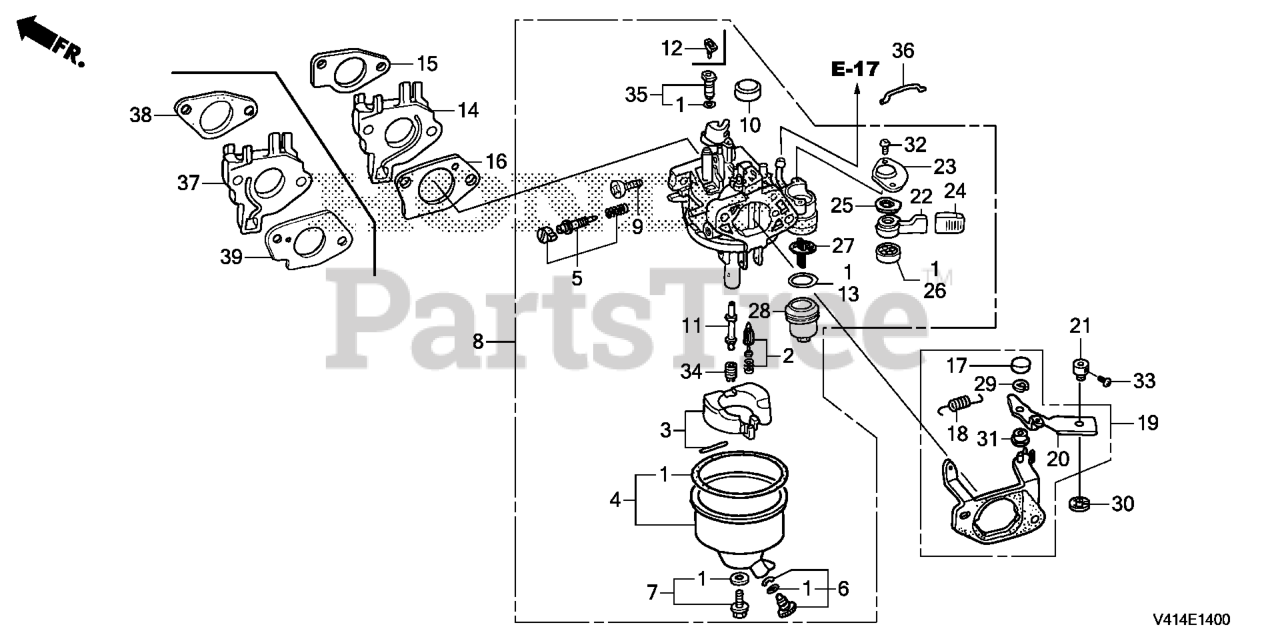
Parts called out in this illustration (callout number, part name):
1	GASKET SET (CARBURETOR NO.)
2	VALVE SET, FLOAT
3	FLOAT SET (CARBURETOR NO.)
4	CHAMBER SET, FLOAT
6	SCREW SET, DRAIN (CARBURETOR NO.)
7	SCREW SET (CARBURETOR NO.)
8	CARBURETOR ASSY. (BE75V A)
9	SCREW, THROTTLE STOP
10	CAP, CHOKE LEVER DUST
11	NOZZLE, MAIN
12	COLLAR, SET
13	GASKET, FUEL STRAINER CUP
17	CAP, CHOKE LEVER
18	SPRING, THROTTLE RETURN
19	STAY ASSY., CHOKE CONTROL (REMOTE)
20	LEVER, CHOKE
21	HOLDER, WIRE
22	LEVER, VALVE
23	PLATE, LEVER SETTING (CARBURETOR NO.)
24	CAP, LEVER
25	SPRING, PETCOCK LEVER (CARBURETOR NO.)
26	GASKET, VALVE
27	FILTER, CUP (CARBURETOR NO.)
28	CUP, FUEL STRAINER
29	E-RING (4MM)
30	CIRCLIP (5MM) Use from Engine SN 2327377.
31	BUSH, CHOKE LEVER
32	SCREW, PAN (3X6)
33	SCREW, PAN (4X6)
34	JET, MAIN (#85) Use up to Engine SN BE81B B.
34	JET, MAIN (#88) Use up to Engine SN BE81B B.
34	JET, MAIN (#90) Use from Engine SN BE81B C.
35	JET SET, PILOT (#40) (ADVENTURE GREEN) (CARBURETOR NO.)
36	ROD, CHOKE
37	INSULATOR, CARBURETOR
38	GASKET, INSULATOR
39	GASKET, CARBURETOR
